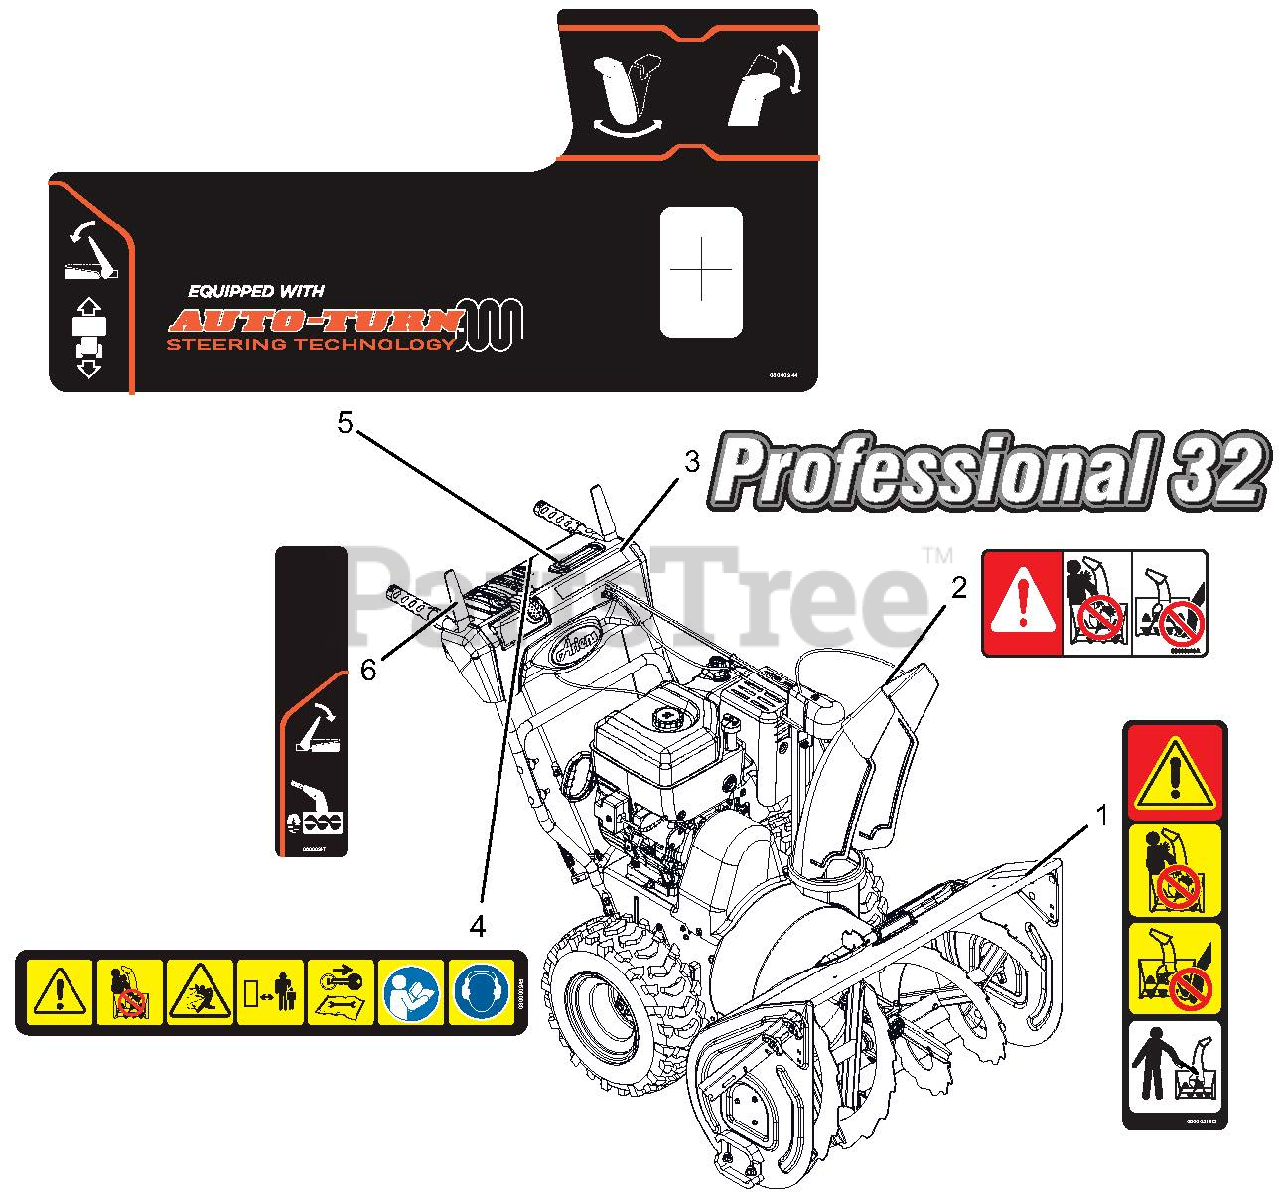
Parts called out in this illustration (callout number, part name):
1	DECAL, DANGER - ROTATING PARTS
2	DECAL, DANGER
3	DECAL, PROFESSIONAL 32
4	DECAL,DASH - SAFETY
5	DECAL,CONTROL-LG QT2
6	DECAL,CONTROL-RH CONTROL
